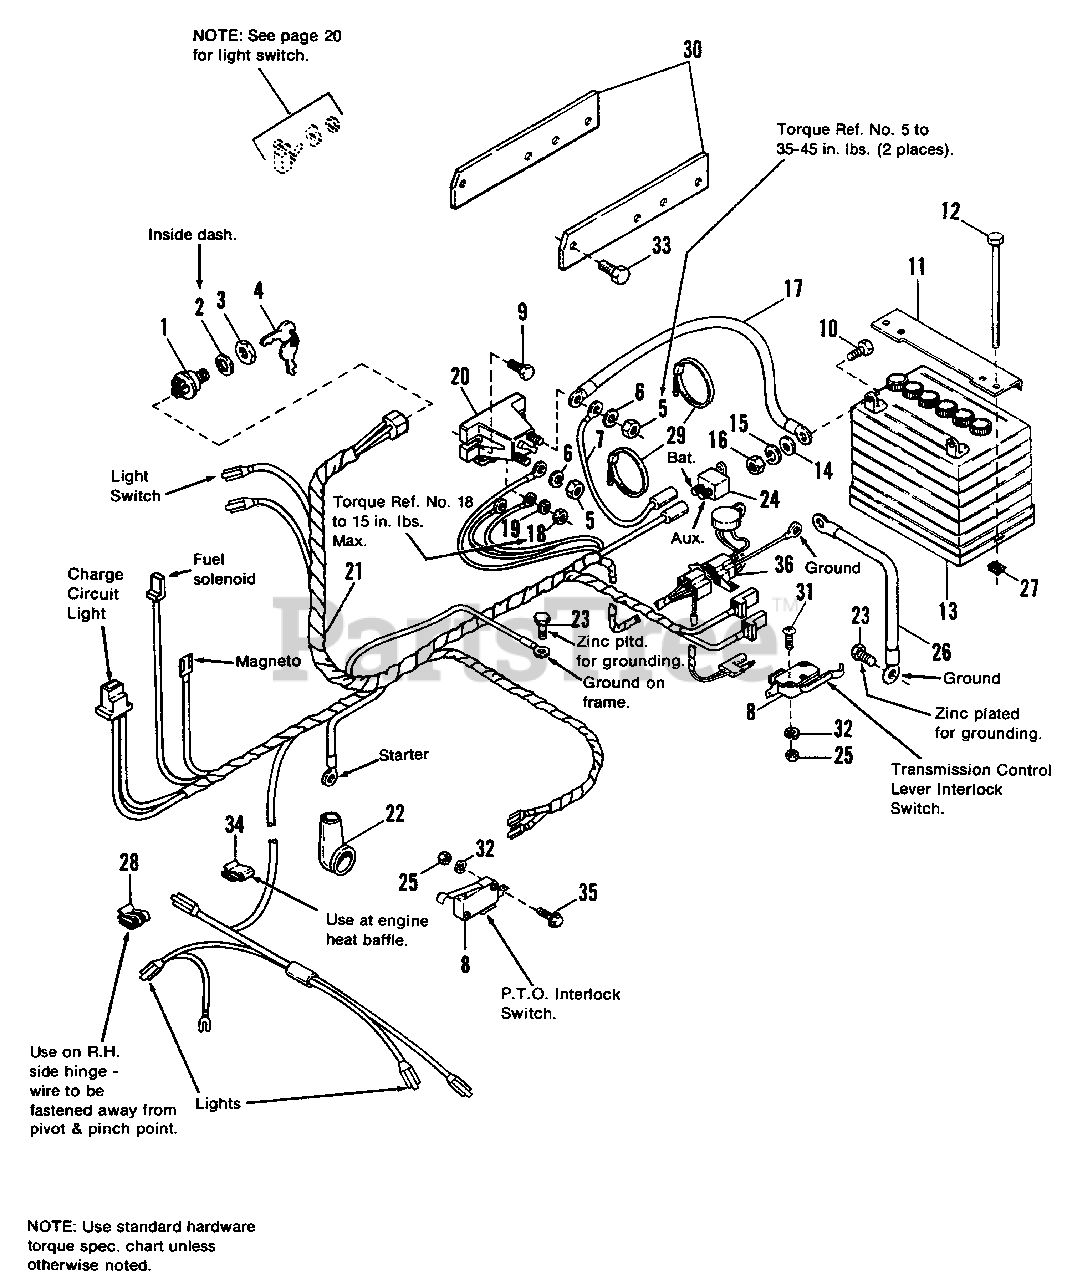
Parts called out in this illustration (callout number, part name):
1	SWITCH, Ignition (Incl. Ref. No. 2, 3 & 4)
2	LOCKWASHER, Internal Tooth, 5/8
3	NUT, 5/8-32
4	KEYS, Set of 2
5	NUT, Hex, 5/16-24
6	LOCKWASHER, 5/16
7	WIRE ASSY. (Circuit Breaker)
8	SWITCH, Interlock
9	SCREW, Taptite, 1/4-20 x 5/8
10	CAPSCREW, Hex, 1/4-20 x 3/4
11	CLAMP, Battery
12	CAPSCREW, Hex, 1/4-20 x 7
13	BATTERY SERVICE KIT, 39 Amp.
14	WASHER, 1/4
15	LOCKWASHER, 1/4
16	NUT, Hex, 1/4-20
18	NUT, Hex, #10-32
19	LOCKWASHER, Ext. #10
20	SOLENOID
21	HARNESS, Wiring
22	COVER, Terminal
23	SCREW, Taptite, 1/4-20 x 3/8
24	CIRCUIT BREAKER
25	NUT, Hex, #5-40
27	NUT, Retainer, 1/4-20
28	WIRE CLIP
29	TIE, Self-Locking
30	BRACE, Shift Panel
31	SCREW, Rd. Hd., Phil #5-40 x 3/4
32	LOCKWASHER, #5
33	SCREW, Taptite, 1/4-20 x 3/8
34	WIRE CLIP
35	SCREW, Taptite, #5-40 x 3/4
36	MODULE-DSI INTERLOCK
